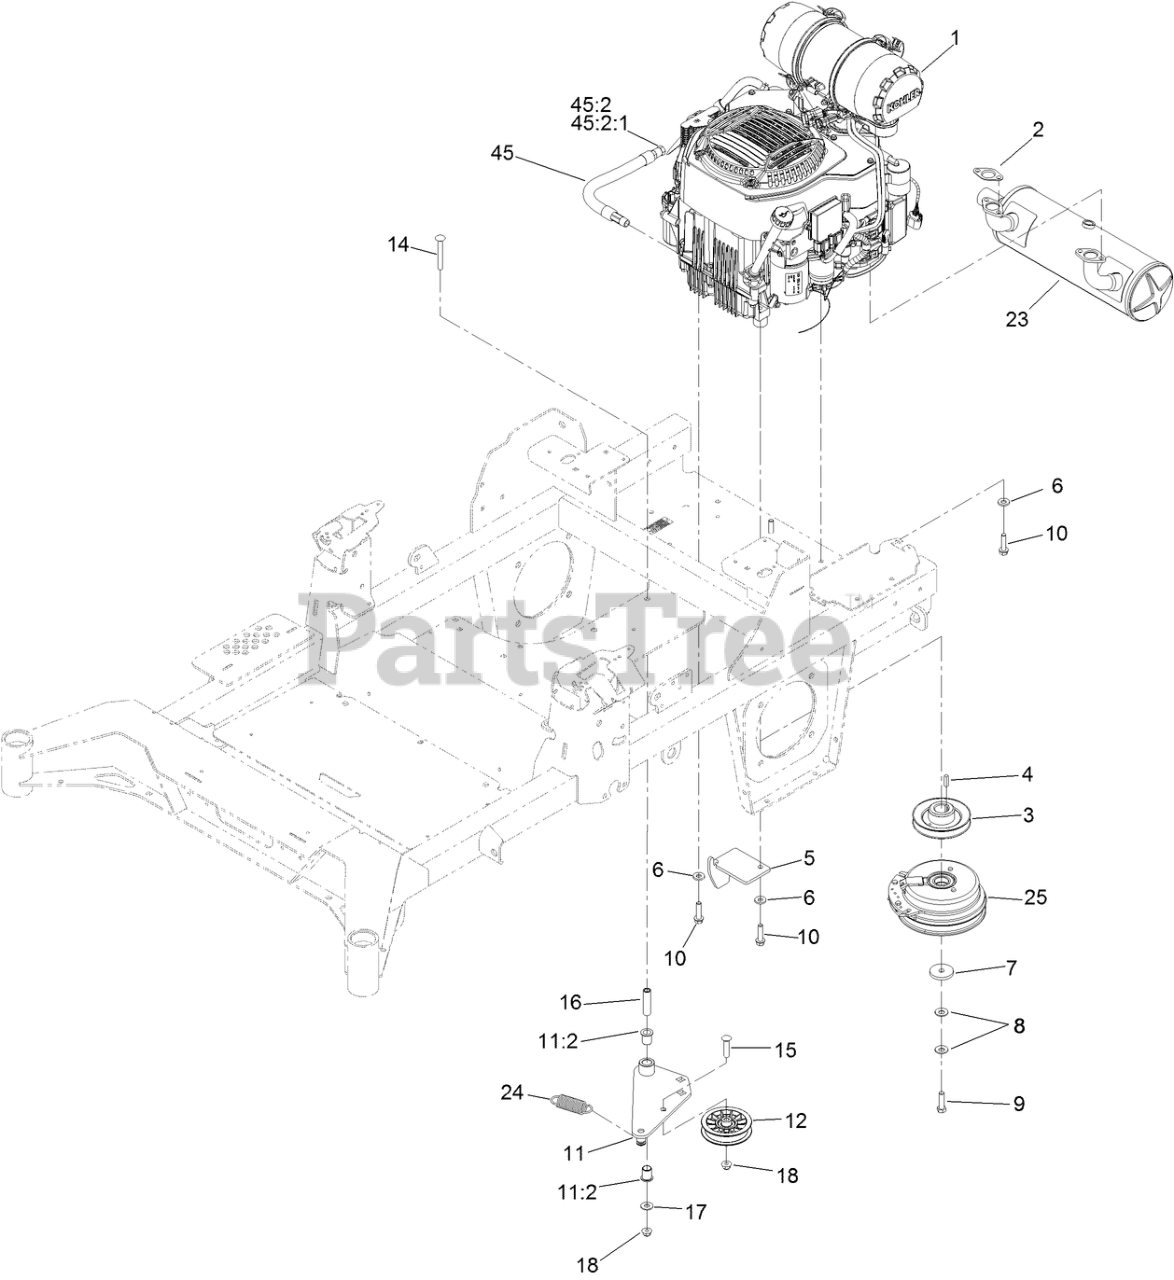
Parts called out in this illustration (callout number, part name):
1	ENGINE-KOHLER
2	GASKET-EXHAUST
3	SHEAVE, W/HUB
5	ANCHOR-CLUTCH
6	WASHER-BELLEVILLE
7	WASHER-CLUTCH
8	WASHER-SPRING
9	SCREW-HH, W/LOCTITE
10	SCREW-HWH
11	IDLER ARM ASM
11:2	BUSHING-FLANGE
12	PULLEY-FLAT IDLER
14	SCREW-CARR
15	SCREW-CARR
16	BUSHING, IDLER PIVOT
17	WASHER-FLAT
18	NUT-HF, NI
23	MUFFLER-KOHLER EFI
24	SPRING-IDLER
45	OIL DRAIN HOSE ASM
45:2	PLUG-HH
45:2:1	O-RING
